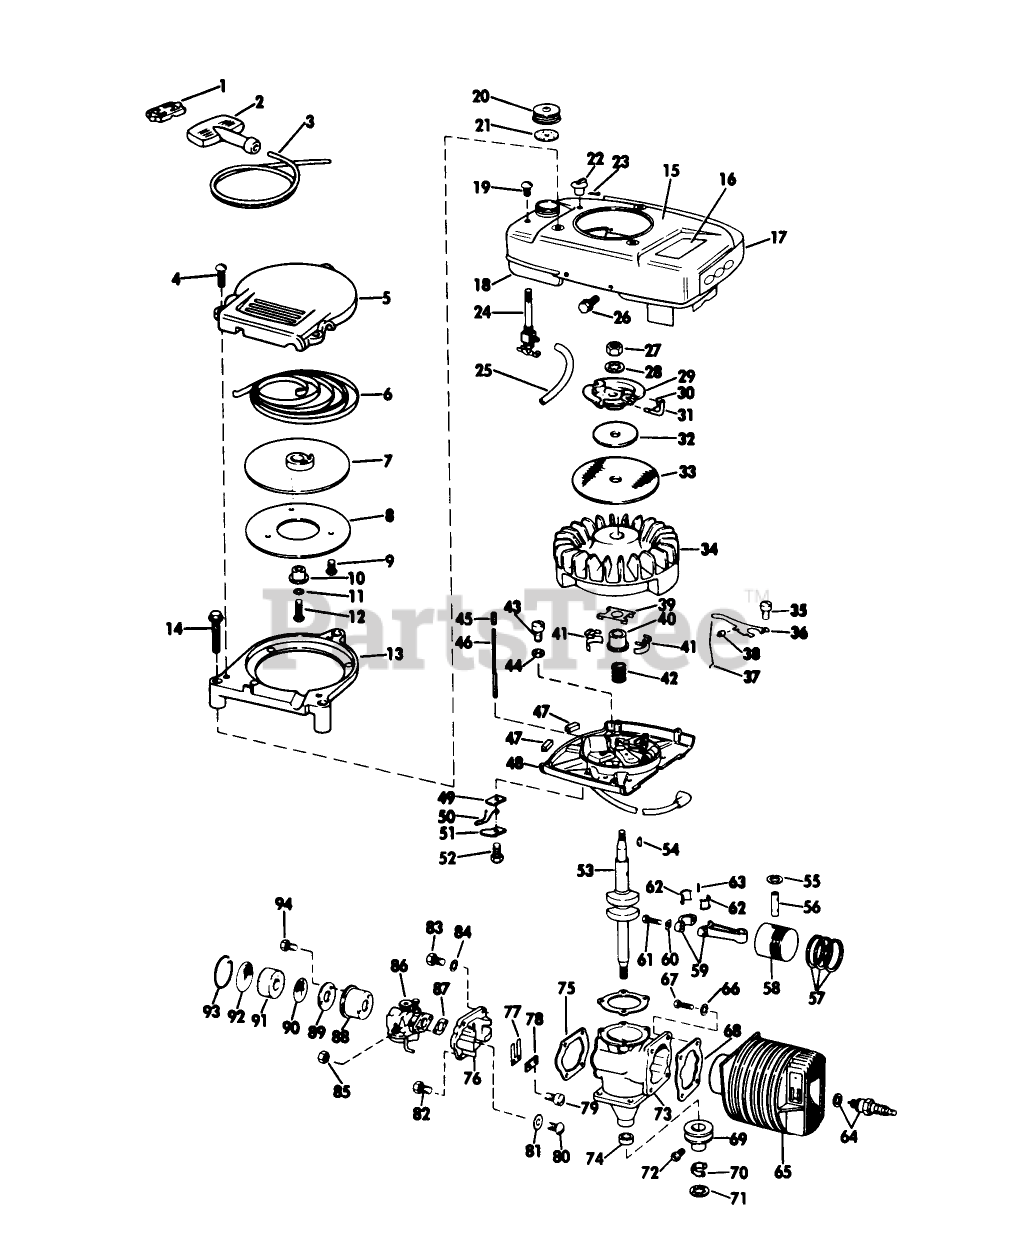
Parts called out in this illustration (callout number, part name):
6	RECOIL SPRING
8	Plate-Pulley
22	KNOB, CHOKE BAR
23	Cotter Pin-Choke Knob
24	VALVE&SCREEN SM
26	SCREW S
31	PIN - STARTER
36	GOVERNER LEVER AY
37	GOVERNOR ROD S
38	WEAR BLOCK S
40	COLLAR S
52	Screw Shut-off Switch
55	RING-RETAINING
62	LINER ASM
68	GASKET S
78	PLATE-BACKUP, REED
82	SCREW S
83	SCREW S
85	STOP NUT
87	GASKET S
89	BACK-UP PLATE
91	ELEMENT
